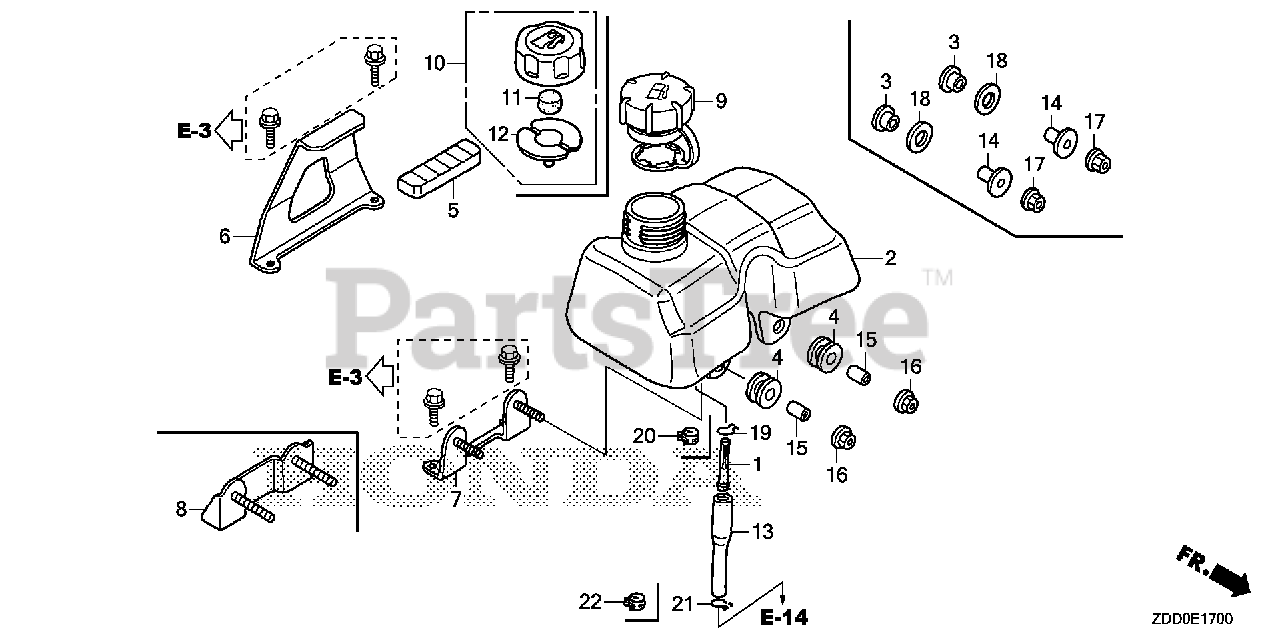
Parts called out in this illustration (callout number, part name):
1	FILTER, FUEL
2	TANK, FUEL
4	RUBBER A, TANK MOUNTING
5	RUBBER B, TANK MOUNTING
6	STAY A, FUEL TANK
7	STAY B, FUEL TANK
9	CAP ASSY., FUEL TANK
13	TUBE, FUEL
15	COLLAR, IGNITION COIL SETTING
16	NUT, FLANGE (6MM)
20	CLIP, TUBE (10.5MM)
22	CLIP, TUBE (D8)
